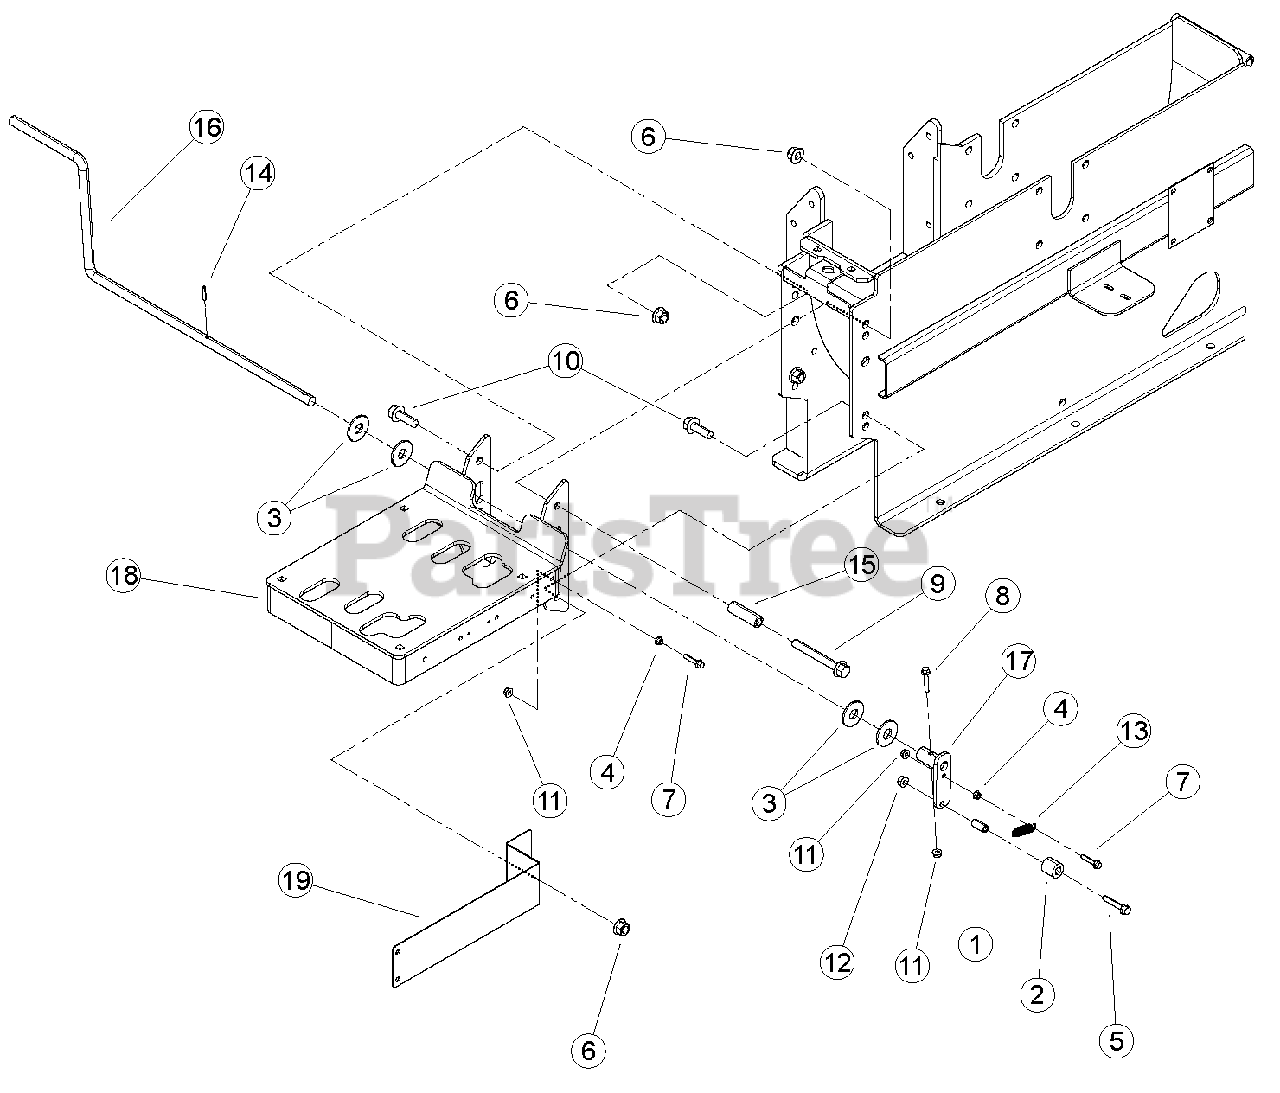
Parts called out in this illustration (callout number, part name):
1	SPACER, 0.5 X 1.00
2	ROLLER, 0.5 X 1.00 X 1.00 NYLON
3	WASHER, 5/8" FLAT ZP
4	NUT, 1/4"-20 SERRATED FLANGE NC ZP
5	BOLT, 5/16 X 1-3/4 FLANGE NC
6	NUT, 1/2-13 NYLOCK FLANGE
7	BOLT, 1/4 X 1-1/4 FLANGE NC
8	BOLT, 1/4 X 1-1/2 FLANGE NC
9	BOLT, 1/2-13 X 4 HWH GR5 CZP
10	BOLT, 1/2-13 X 1-1/2 GR5 FLANGE NC
11	NUT, 1/4-20 NYLOCK-FLANGE
12	NUT, 5/16-18 NYLOCK-FLANGE
13	SPRING, 1/2 X 2.00 LG ZP
14	PIN, ROLL 3/16 X 1"
15	SPACER, .75 X 2.06
16	HANDLE, ENGAGEMENT
17	WELDMENT, SHAFT ENGAGEMENT ARM
18	WELDMENT, ENGINE BASE
19	SHIELD, HYD PUMP
